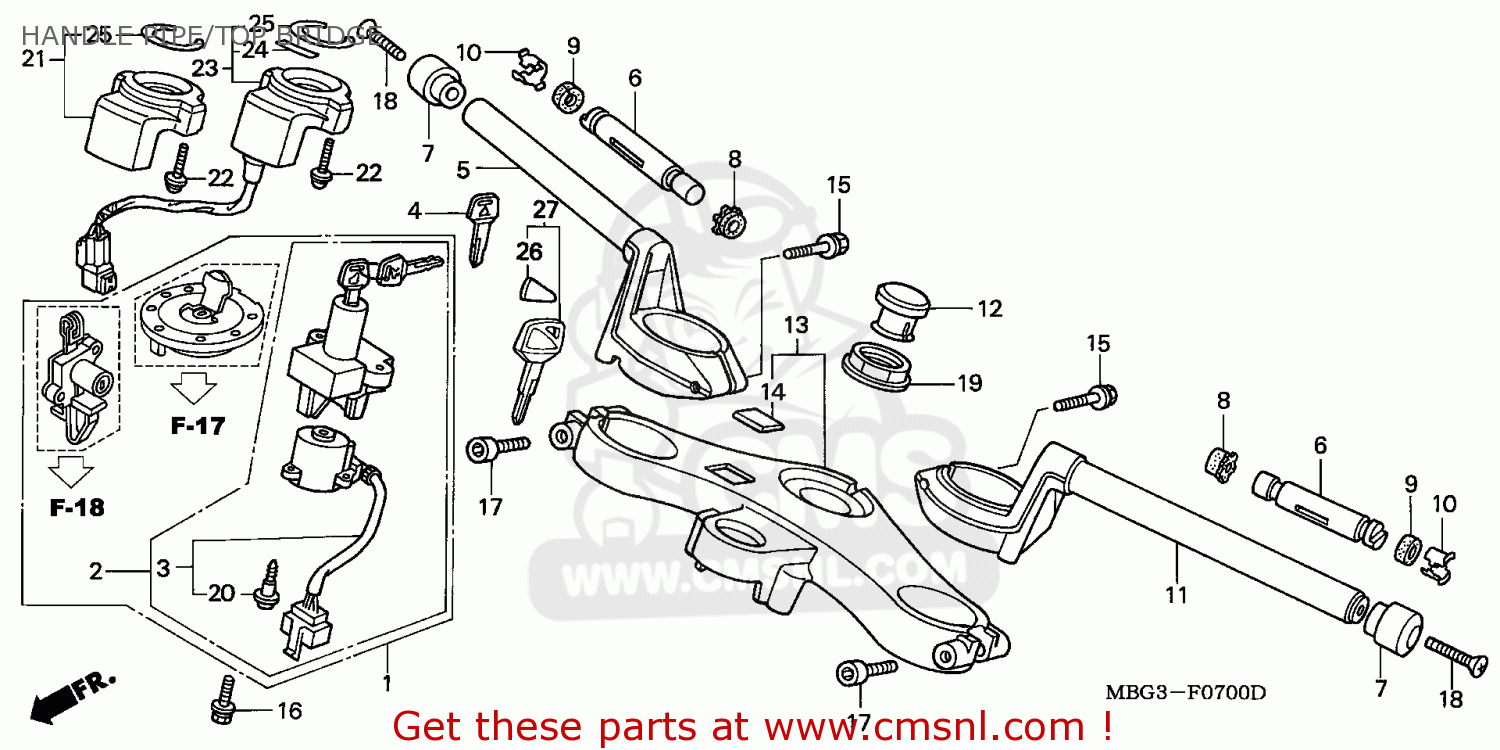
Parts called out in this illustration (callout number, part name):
1	KEY SET
2	SWITCH ASSY,COMB&
3	BASE COMP,CONTACT
4	KEY,BLANK (NO.1)
5	PIPE COMP,R HNDL
6	WEIGHT B,STEERING
7	WEIGHT,STEERING H
8	RUBBER A,HANDLE W
9	RUBBER,HNDL.WT.B
10	SNAPRING,HNDL WT
11	PIPE COMP,L HNDL
12	CAP,STEEPING NUT
13	BRIDGE COMP,FORK
14	EMBLEM,WING MARK
15	BOLT,FLANGE 8X35
16	BOLT,ONE-WAY 8MM
17	BOLT,SOCKET,8X46
18	SCREW,OVAL,6X65
19	NUT,FLANGE.,STEER
20	SCREW,TAPPING,3X1
